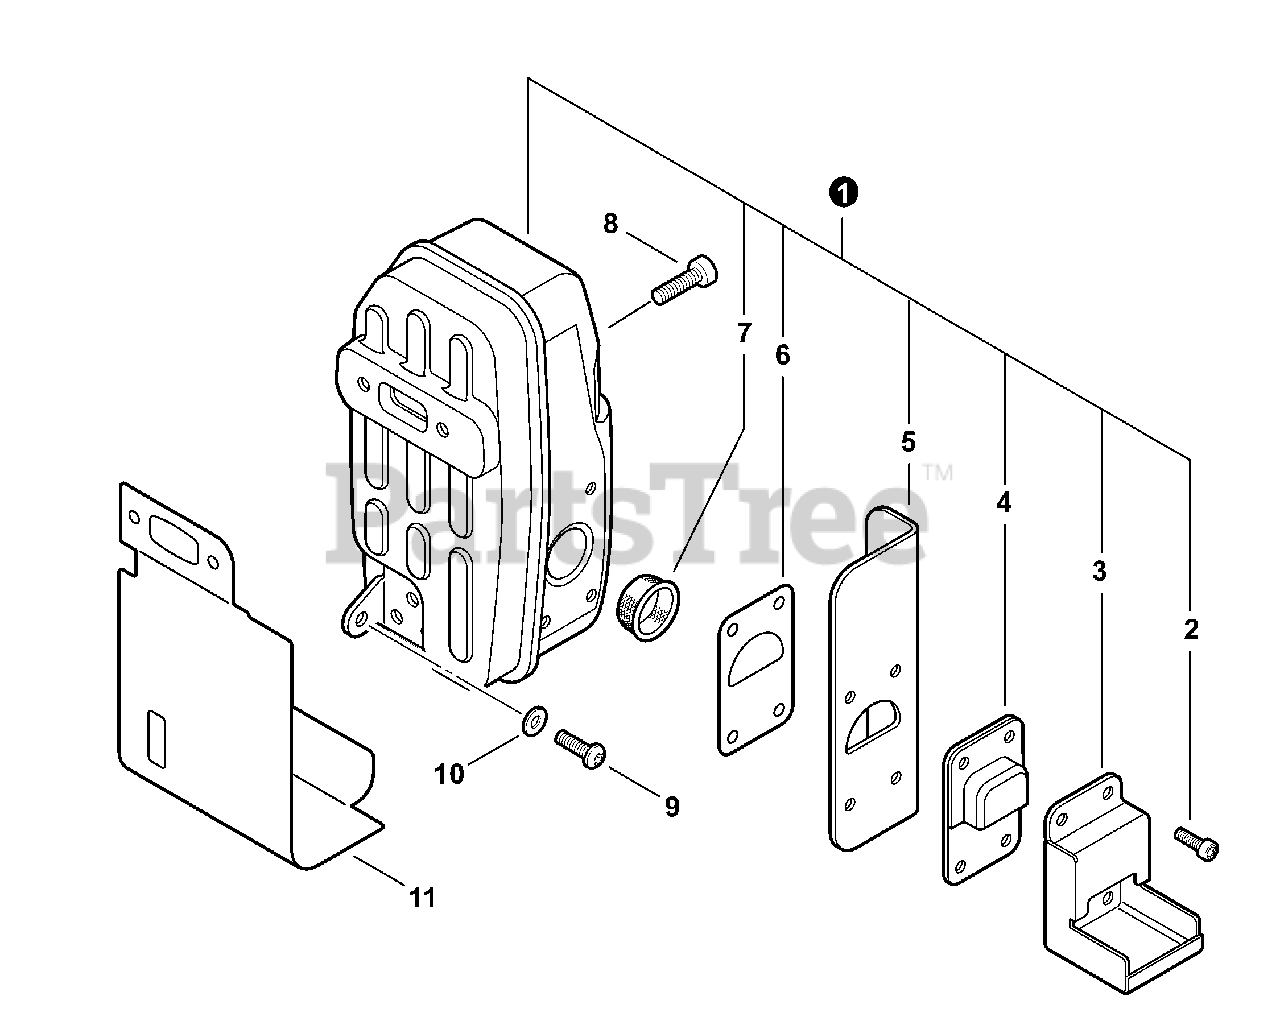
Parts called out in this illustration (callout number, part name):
1	MUFFLER ASSY
2	BOLT, TORX 4×12
3	GUIDE, EXHAUST
4	GUIDE, EXHAUST
5	HEAT SHIELD, EXHAUST
6	GASKET, EXHAUST
7	SCREEN, SPARK ARRESTER
8	BOLT, TORX 6×20
9	BOLT, TORX 5×16
10	WASHER 5.5×16×2T
11	HEAT SHIELD, EXHAUST
